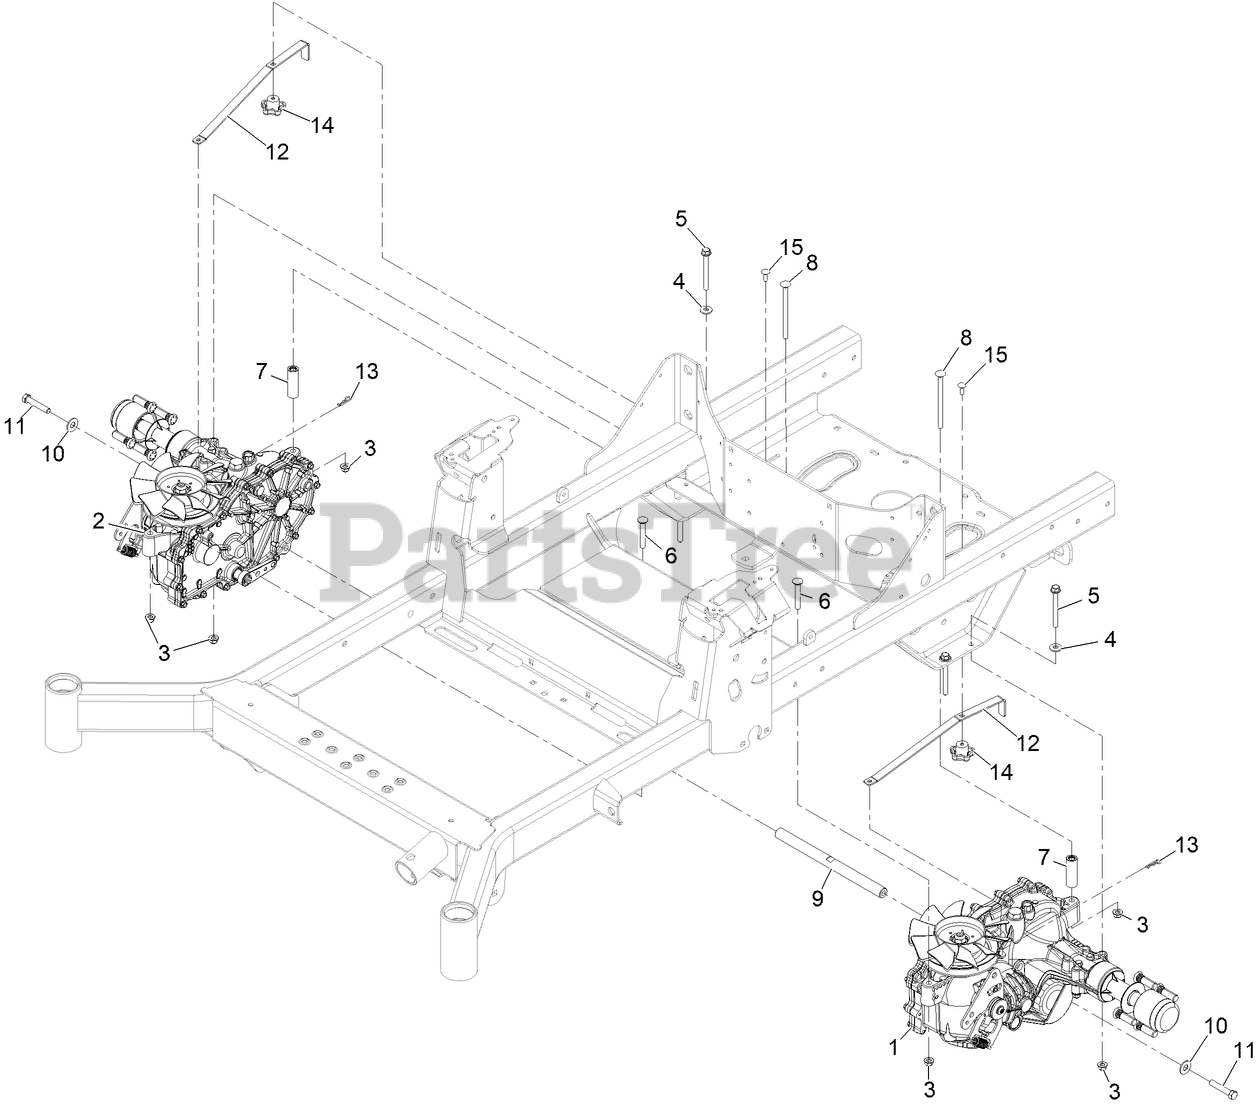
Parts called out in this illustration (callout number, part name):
1	TRANSAXLE ASM
2	TRANSAXLE ASM
3	NUT-HF, NI
4	WASHER-SPRING
5	SCREW-HHF
6	BOLT-CARR
7	SPACER, HYDRO
8	Bolt-Carriage 5/16-18 X 1 1/4
9	SHAFT-SPACER
10	WASHER-FLAT
11	SCREW-HH W/LOCTITE
12	ARM-BYPASS, HYDRO
13	PIN-COTTER
14	KNOB-HANDLE
15	BOLT-CARR
